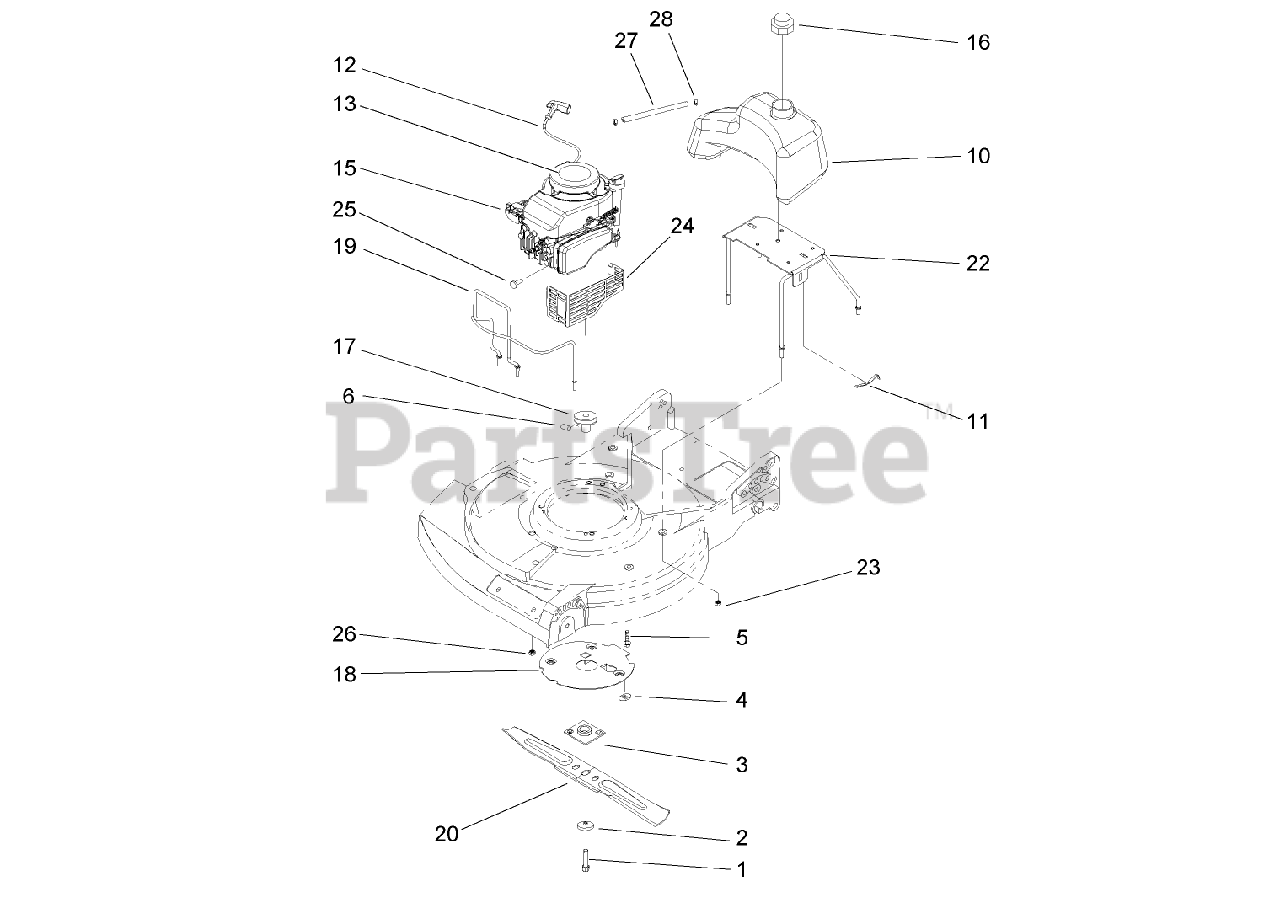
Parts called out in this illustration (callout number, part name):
1	BOLT-BLADE
2	SPACER-BLADE
3	PLATE AND COLLAR ASM
4	PUSH NUT
5	SCREW-MOUNT, ENGINE
6	SCREW-SET
10	TANK-FUEL
11	SPRING
12	STOP-ROPE
13	DECAL-RECOIL
16	GAS CAP ASM
17	PULLEY
18	SHIELD-GRASS
19	GUARD-MUFFLER
20	Blade
20	BLADE-20.88 INCH
22	TANK BRACKET ASM
23	NUT-LOCK, NI
24	SHIELD-MUFFLER
25	SCREW-TAPTITE
26	NUT-LOCK, CONE
27	GAS-LINE
28	CLAMP-HOSE
